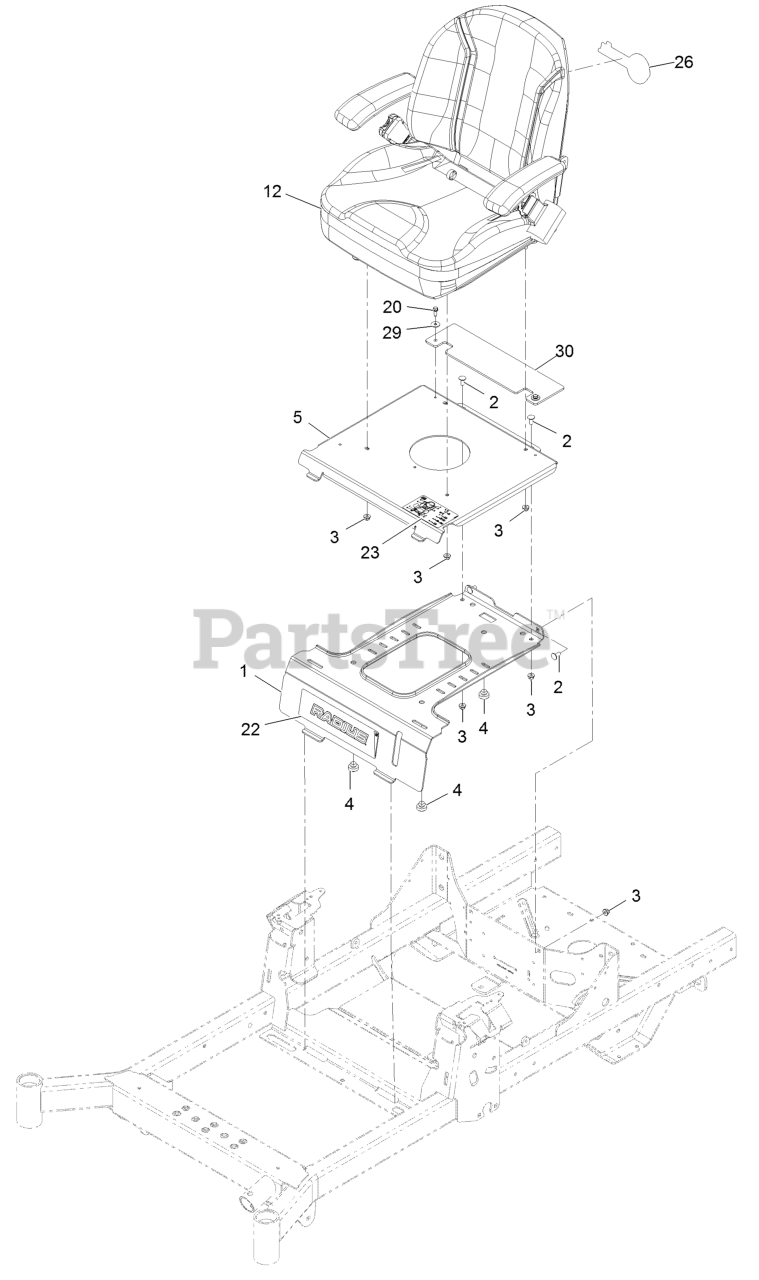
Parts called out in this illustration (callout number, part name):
1	Plate-Retainer, Tank
2	Bolt-Carriage 5/16-18 X 3/4 Short Neck
3	Nut-Nyloc 5/16-18 Flg
4	Bumper-Rubber
5	Plate-Seat, Fixed
12	ASM-Seat Exmark
20	Screw-HWH 1/4-20 X 3/4
22	Decal-Radius Logo
23	Decal-Service Aid
26	Decal-Exmark Logo
29	Washer-Flat
30	Guard, Rubber
